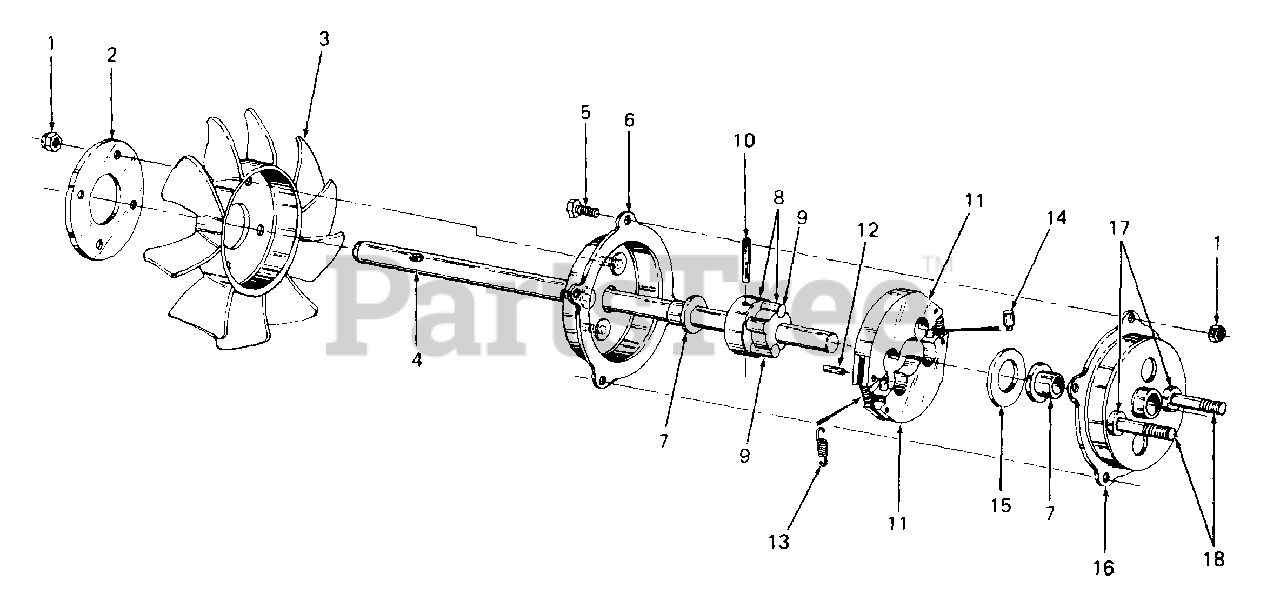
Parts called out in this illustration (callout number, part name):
1	Nut, Hex Patch Lock, 1/4-20
2	Spacer, Fan
3	Fan, Cooling
4	Shaft, Drive
5	Screw, Hex Cap, 1/4-20 X .50 Lg GR5
6	Cover Assy, Clutch
7	Bearing, Flange, .630 ID
8	Hub Assy, Clutch
10	Pin, Slotted Roll, 1/4 Dia X 2.25 Lg
11	Shoe Assy, Clutch
12	Pin, Spirol Spring, 1/8 Dia X 5/8 Lg
13	Spring, Extension, .31 Dia X .85 Lg
15	Washer, Flat, .635 X 1.585 X .062 Thk HDN
16	Housing, Clutch
17	Spacer, .385 X .88 X .25 Lg
18	Bolt, Ribbed Neck, 3/8-24 X 1.5 Lg GR5
